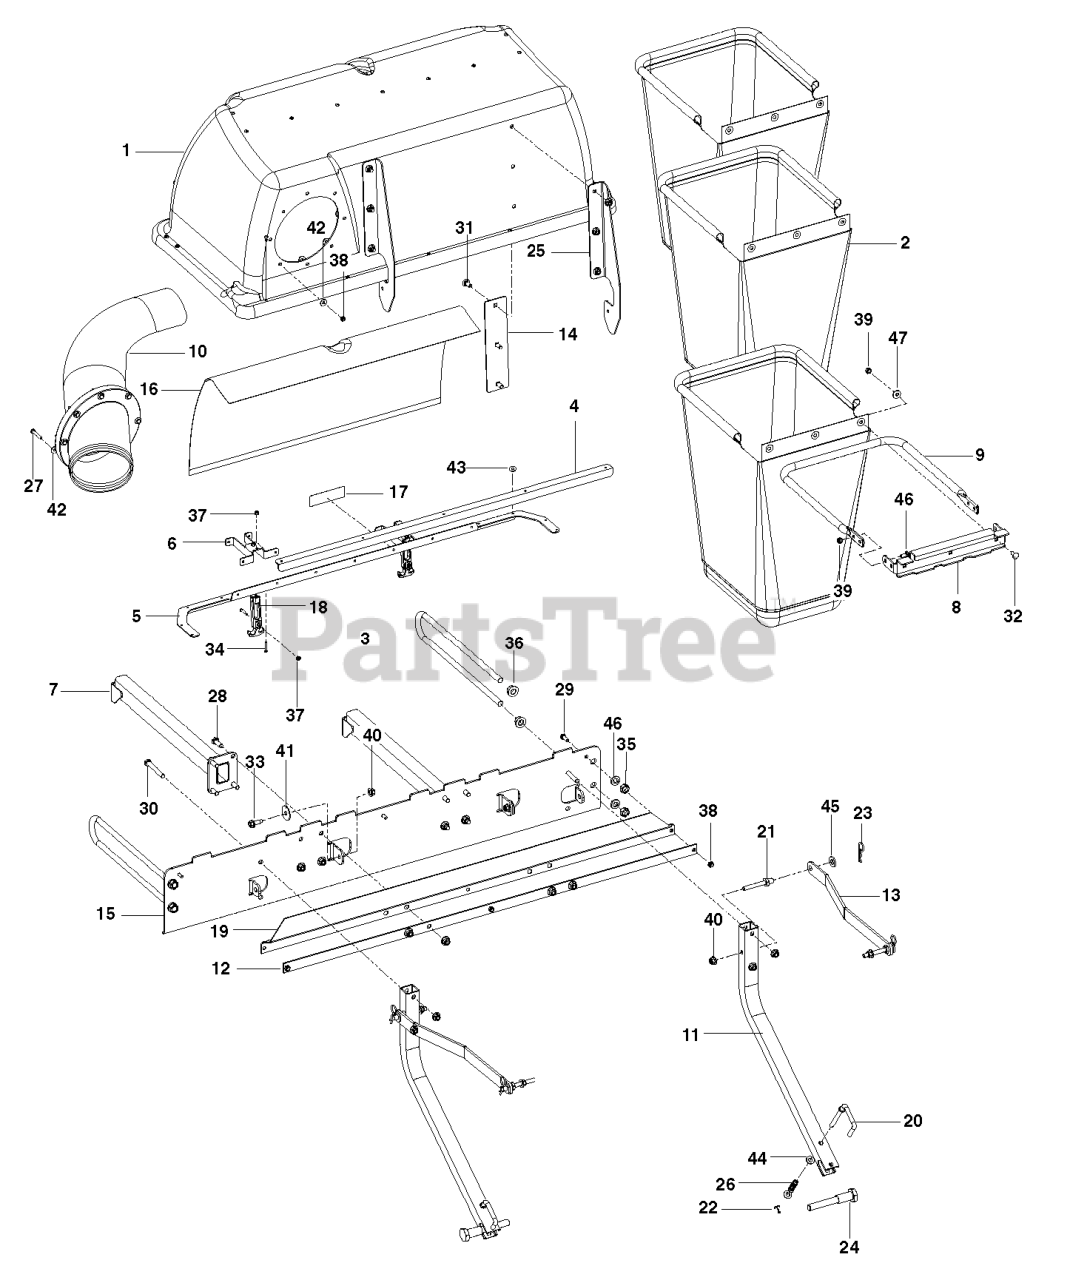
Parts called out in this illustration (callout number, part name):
2	BAG, SMALL
3	SUPPORT, OUTER
4	SUPPORT, HOOD-RR, BLK
5	HOOD SUPPORT
6	SUPPORT, DRAW LATCH
7	SUPPORT ARM WELDMENT
8	HANGER, BAG, BLK
9	TUBE BAG FRAME
11	TUBE, HITCH, BLK
12	SEAL STRAP
13	STRAP, BLK
14	MOUNT PLATE
15	PLATE, MOUNT, BLK
16	MESH, POLY DIAMOND
17	DECAL, VENTILATION
18	DRAW LATCH, FLEXIBLE T-HANDLE
19	SEAL, RUBBER
20	PIN, RETENTION
21	PIN, MOUNT
22	COTTER PIN
23	HAIRPIN #4
24	BOLT, PIVOT
25	BRACKET, HINGE, BLK
26	SPRING, COMPRESSION
27	HCS.1/4-20 X 1-3/4 GR 5 ZD
29	BOLT
30	BOLT.HEX
31	BOLT D
32	RP BOLT 5/16-18 X3/4 ZN/YEL GR
33	SCREW GTV
34	SCR, #10-24 X 1-1/8
35	NUT 1/2-13 HEX JAM
36	NUT 1/2-13 HEX
37	NUT 10-24 NYLOC
38	LOCKNUT.NYLOC.1/4-20
39	5/16-18 NYLOC FLANGE NUT
40	NUT 3/8-16 HEX FLG NYLOC ZD
41	WASHER, FRICTION
42	WASHER
43	WASHER, #10 MACH SCR BLK OX
44	WASHER
45	WASHER STEEL
46	WASHER 1/2" SPLIT LOCK
47	WASHER 5/16 FLAT
